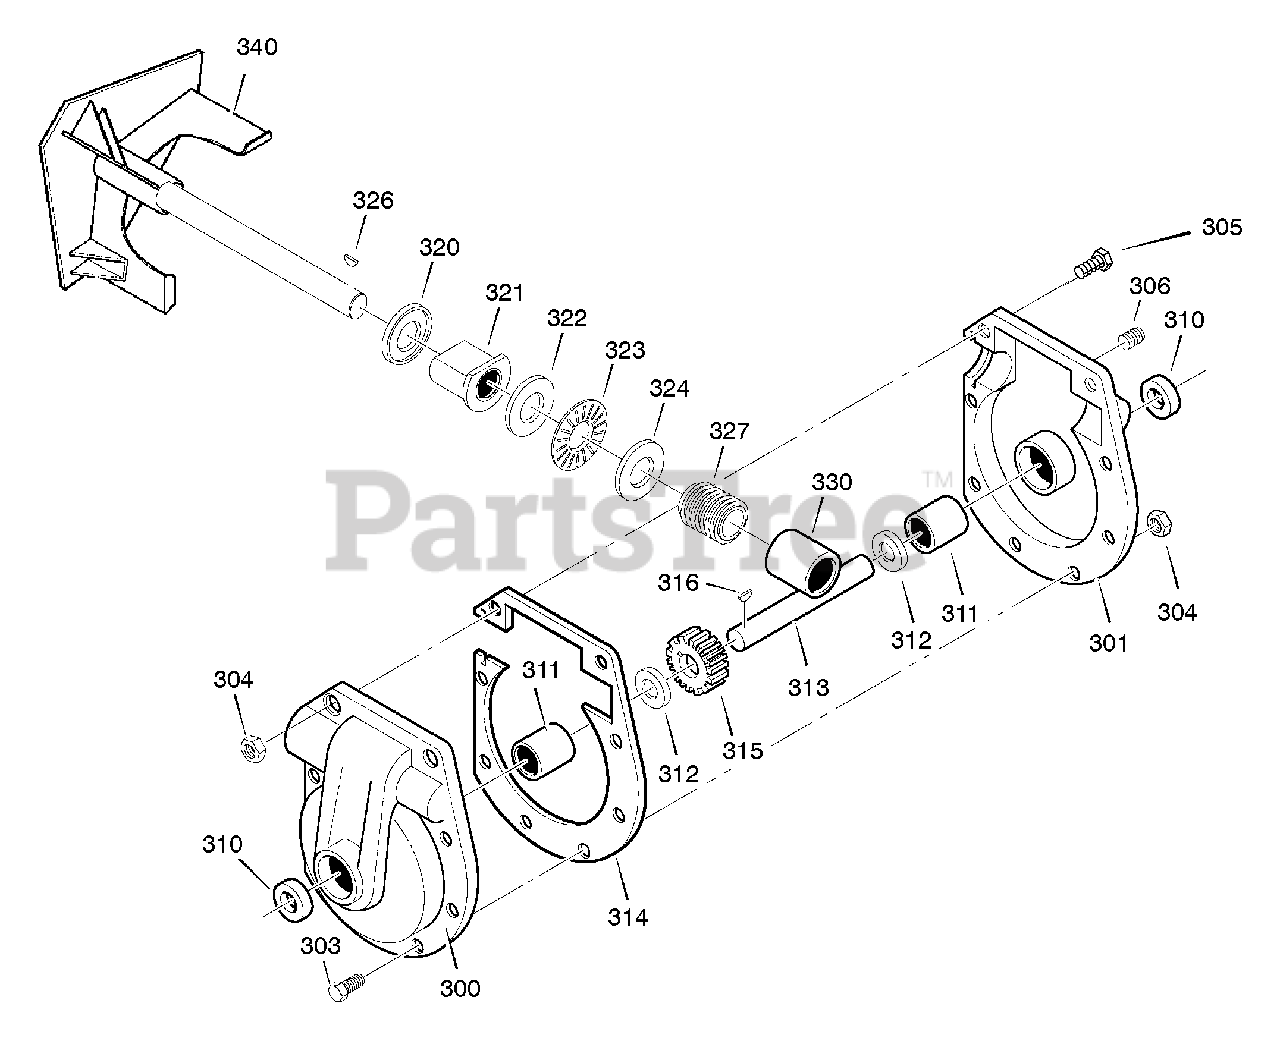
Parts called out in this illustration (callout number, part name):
300	CASE, GEAR, RH
301	CASE, GEAR, LH
303	SCREW, 5/16-24 x 1.00
304	NUT, 5/'16-24
305	SCREW, 5/16-24 x 1.50
306	PLUG, PIPE 0.25-18
310	SEAL, OIL
311	BEARING, SLEEVE
312	WASHER, FLAT
313	SHAFT, AUGER OUTPUT
314	GASKET, GEAR BOX
315	WORM GEAR
316	KEY, WOODRUFF #91
320	RING, QUAD 0.924 ID
321	BEARING, FLANGE
322	WASHER, FLAT
323	BEARING, ROLLER
324	WASHER, FLAT
330	BEARING, SLEEVE
340	IMPELLER
